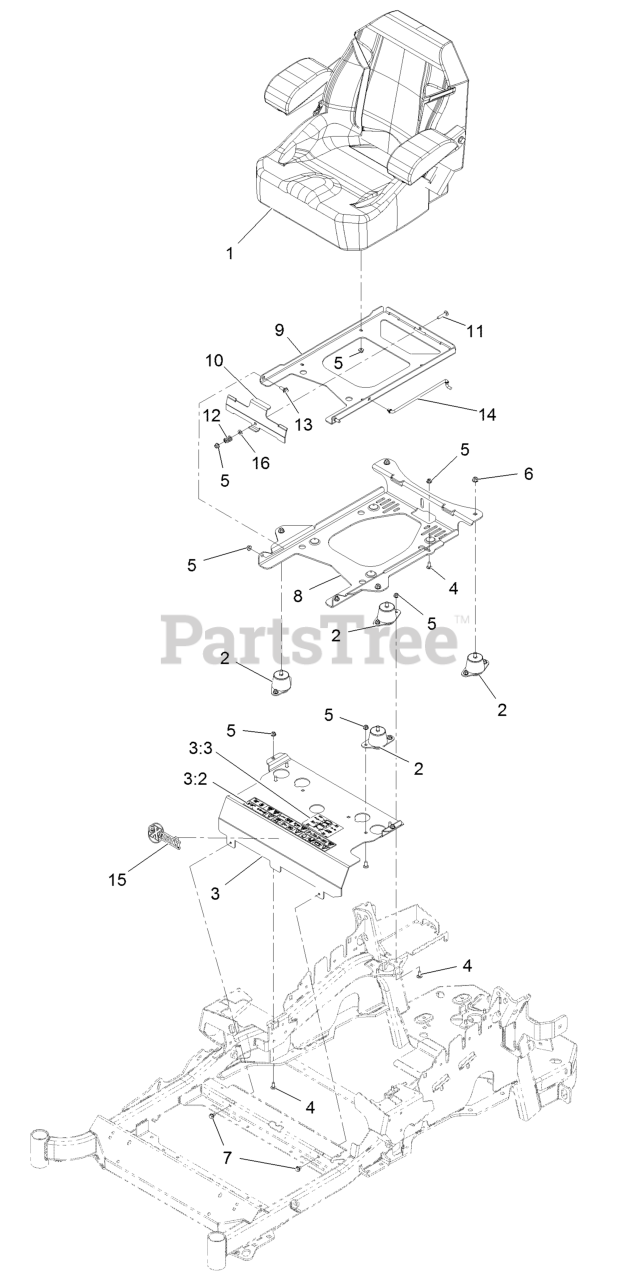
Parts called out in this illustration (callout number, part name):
2	ISOLATOR-SEAT
3	MOUNT-SEAT
3:2	DECAL-CONSOLE
3:3	DECAL-SERVICE AID
4	SCREW-CARR
5	NUT-HF, NI
6	NUT-HF, NI
8	PLATE-TILT, SEAT SUPPORT
9	PLATE-FRAME, SEAT
10	PLATE-LATCH, SEAT
11	BOLT-CARR
12	SPRING-COMPRESSION
13	SCREW-SHOULDER
14	ROD-PROP
16	WASHER-PLAIN
